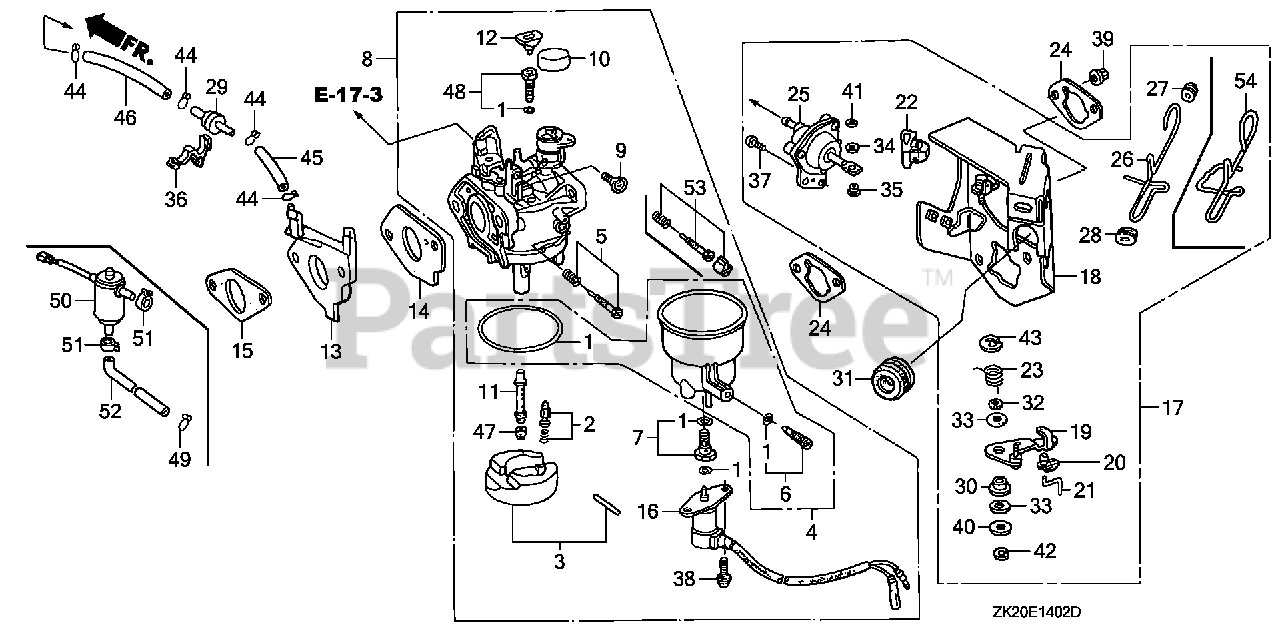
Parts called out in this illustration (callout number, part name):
1	GASKET SET
2	VALVE SET, FLOAT
4	CHAMBER SET, FLOAT
5	SCREW SET, PILOT (CARBURETOR NO.)
6	SCREW SET, DRAIN
8	CARBURETOR ASSY. (BE20B A)
8	CARBURETOR ASSY. (BE72L A)
9	SCREW, THROTTLE STOP
10	CAP, CHOKE DUST
11	NOZZLE, MAIN
12	COLLAR, SETTING (CARBURETOR NO.)
13	INSULATOR, CARBURETOR
14	GASKET, CARBURETOR
15	GASKET, INSULATOR
16	VALVE ASSY., SOLENOID
17	STAY ASSY., MANUAL CHOKE
18	STAY, SOLENOID
19	LEVER, CHOKE
20	JOINT, ROD
21	ROD, CHOKE
22	STOPPER, CHOKE ROD
23	SPRING, MANUAL CHOKE
24	GASKET, AIR CLEANER
25	DIAPHRAGM ASSY.
26	ROD, CHOKE CONTROL
27	GROMMET, CHOKE ROD
28	GUIDE, CHOKE ROD
29	VALVE, DASHPOT CHECK
30	BUSH, ARM PIVOT
31	GROMMET, FENDER
32	WASHER, CHOKE LEVER
33	SEAL, CHOKE LEVER
34	WASHER, THRUST (2.7X8)
35	COLLAR, LEVER
36	CLIP, WIRE HARNESS
37	SCREW, PAN (5X12)
38	SCREW-WASHER (5X12) (CARBURETOR NO.)
39	NUT, FLANGE (6MM)
40	WASHER, PLAIN (5MM)
41	E-RING (2MM)
42	E-RING (4MM)
43	E-RING (7MM)
44	CLIP, TUBE (B7)
45	BULK HOSE, VACUUM (3.5X8000) (3.5X65)
46	BULK HOSE, VACUUM (3.5X8000) (3.5X130)
47	JET, MAIN (#80) (CARBURETOR NO.)
47	JET, MAIN (#75) (CARBURETOR NO.)
47	JET, MAIN (#78) (CARBURETOR NO.)
47	JET, MAIN (#82) (CARBURETOR NO.)
48	JET SET, PILOT (#45) (CARBURETOR NO.)
53	SCREW SET, PILOT (CARBURETOR NO.)
